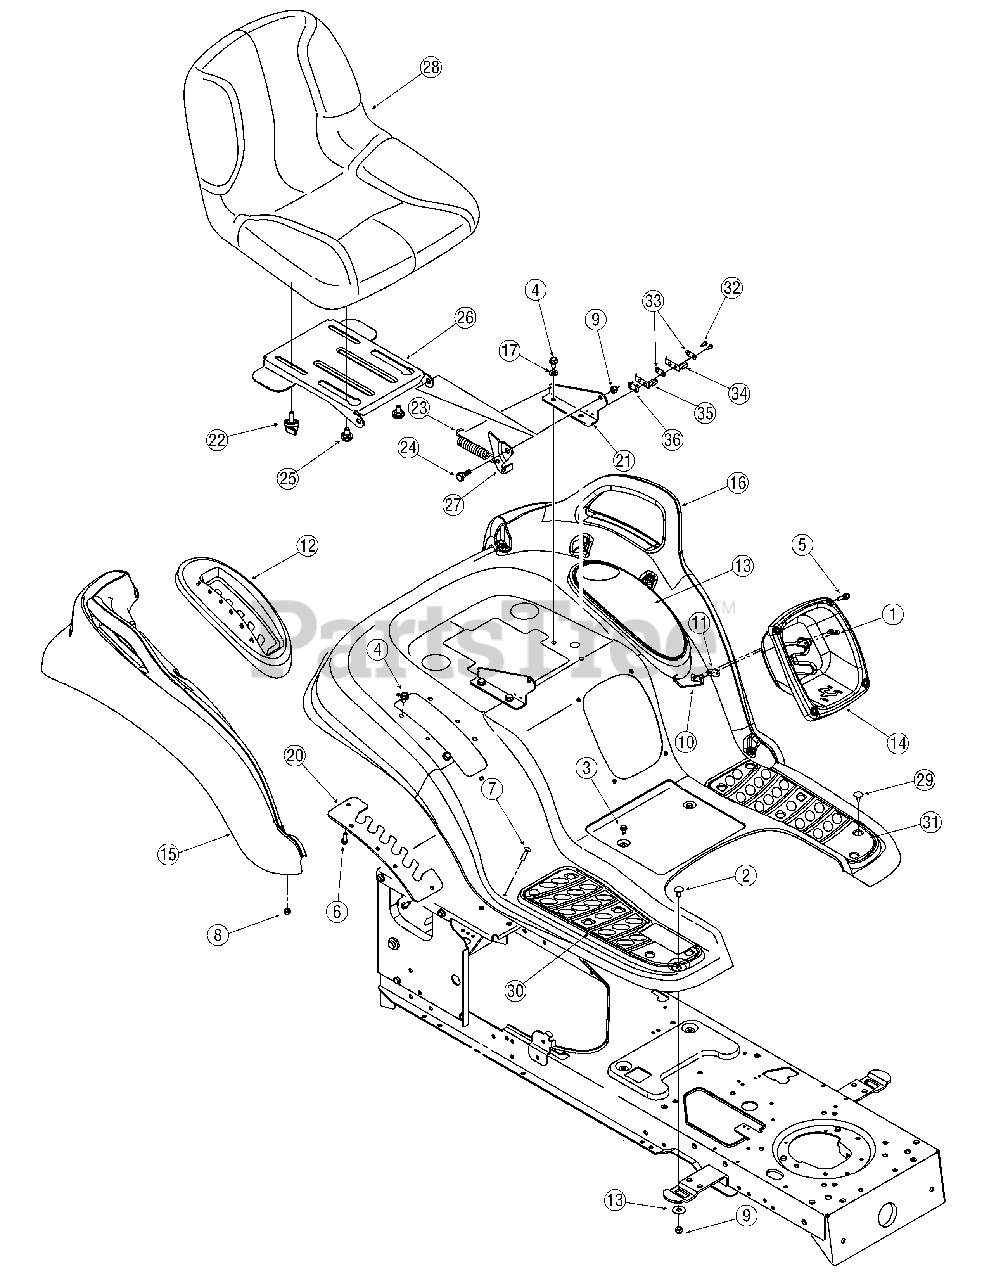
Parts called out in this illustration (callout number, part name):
1	Screw, #8-18, 0.500
2	Bolt, Carriage, 5/16-18, .750 Gr1
3	Screw, /4-20, 0.500
4	Screw, 5/16-18, 0.625
5	Screw, 1/4-20, 1.000
6	Screw, 1/4-15, 0.750
7	Screw, Carriage, 1/4-20, 1.00, Gr1
8	Nut, Sems, 1/4-20
9	Nut, Flange Lock, 5/16-18, GrF, Nylon
10	Switch, Spring
11	Plate, Insulator Nut
12	Cover, Lift Lever
13	Cover, w/ Cup Holder
13	Washer Flat,.344 x 1.0 x .063
14	Cover, Shift
15	Fender Flare, RH
16	Fender Flare, Fender, LH
17	Washer, Lock, 5/16 Ext. Tooth
18	Washer, Flat, .344 x 1.0 x .063
22	Knob, 3/8-16, .875
23	Spring, Extension, .80 Dia x 4.6 Lg.
24	Shoulder Screw .437 x .286 Lg
25	Shoulder Screw, .625 x .145, 3/8-16
27	Bracket, Seat Lift
28	Seat, High Back
29	Clip, Ratchet, .250 Dia
30	RH Foot Pad
31	LH Foot Pad
32	Screw, #8-18 x .50
33	Plate, Insulator
34	Spring Switch, Outer
35	Spring Switch, Inner
36	Plate, Insulator Boss
